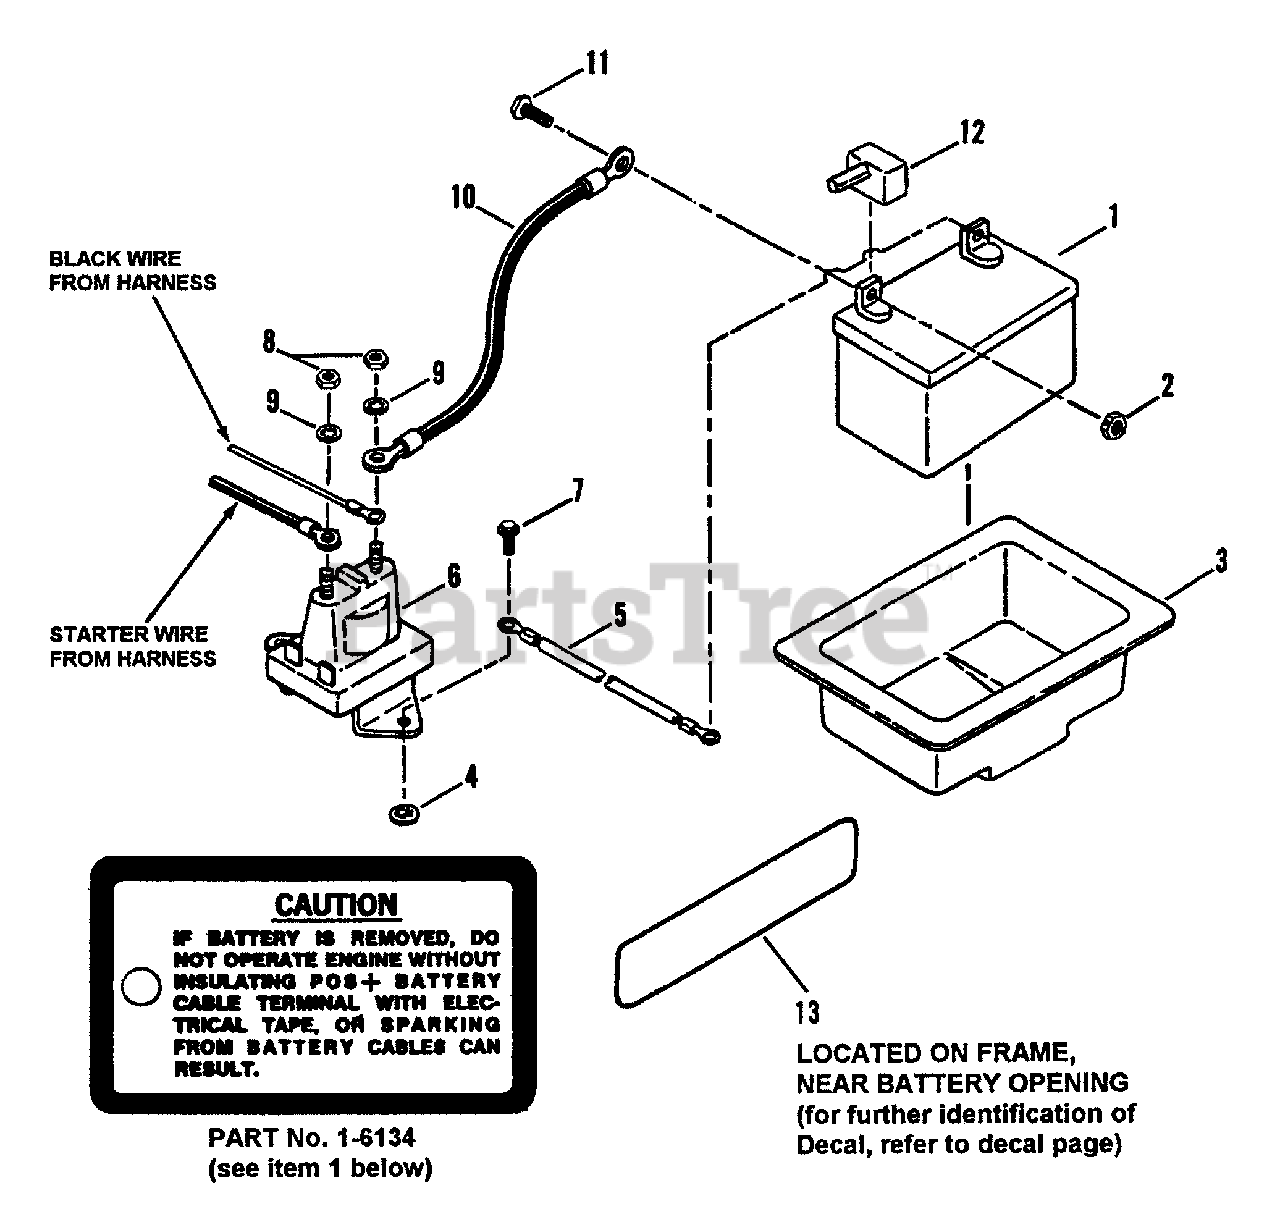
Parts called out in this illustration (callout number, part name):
1	KIT, Battery
2	NUT, 1/4-20 Hex Center Lock, Grade B or 5
3	TRAY, Battery
4	RETAINER, 1/4" Bolt
5	CABLE, Ground (Black)
6	SOLENOID
7	SCREW, 1/4-20 x 1/2" Self-Tapping
8	NUT, 1/4-20 Hex Jam
9	WASHER, 1/4 Internal Tooth Lock
10	CABLE, Positive (Red)
11	SCREW, 1/4-20 x 5/8" Hex Head Cap, Grade 5
12	COVER, Positive Terminal
13	DECAL, Caution, Battery Installation
16134	TAG, Caution
